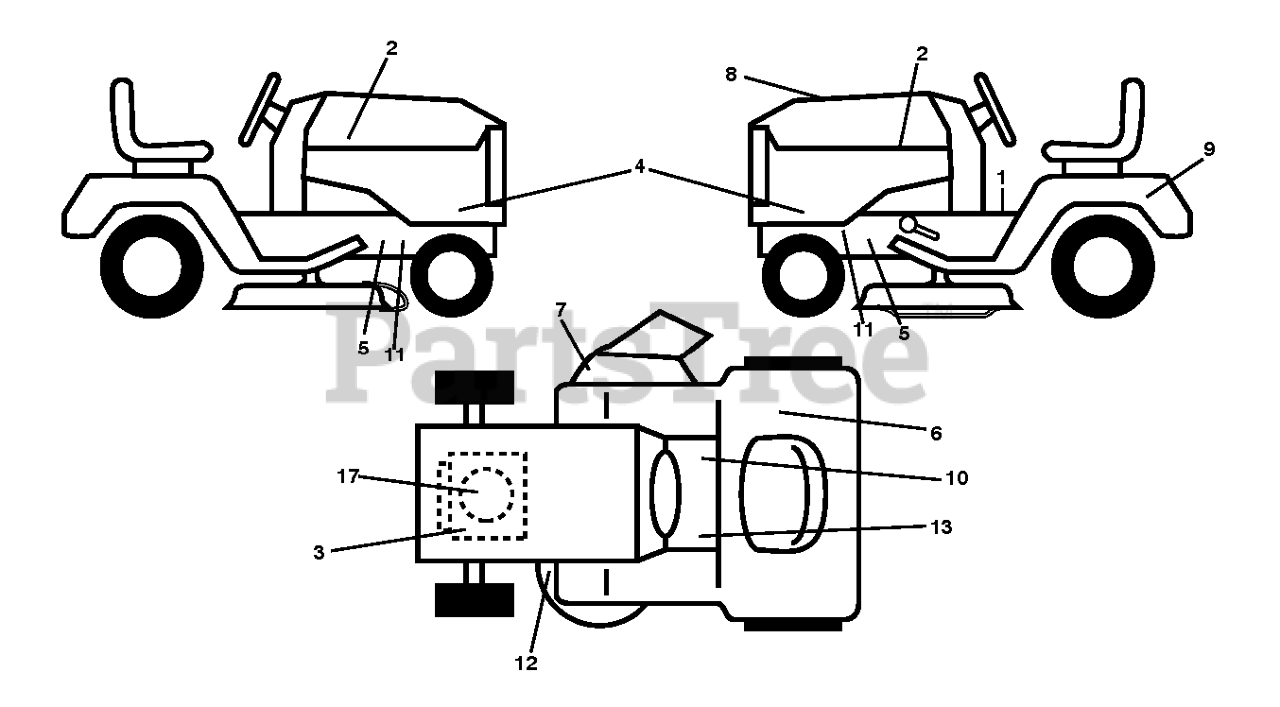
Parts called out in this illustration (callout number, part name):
1	LABEL
2	RP.DECAL.BADGE.170MM.TEXTLOGO
3	DECAL
4	Decal, Hood Panel
6	Decal, Fender 100 DB/CE
7	DECAL, WARN. DEFLECT/CTFGR
9	DECAL BTRY SYMBOLS
10	DECAL PARK BRAKE
12	Decal, Mower V-Belt Schematic
13	DECAL
17	Decal, BS Engine
